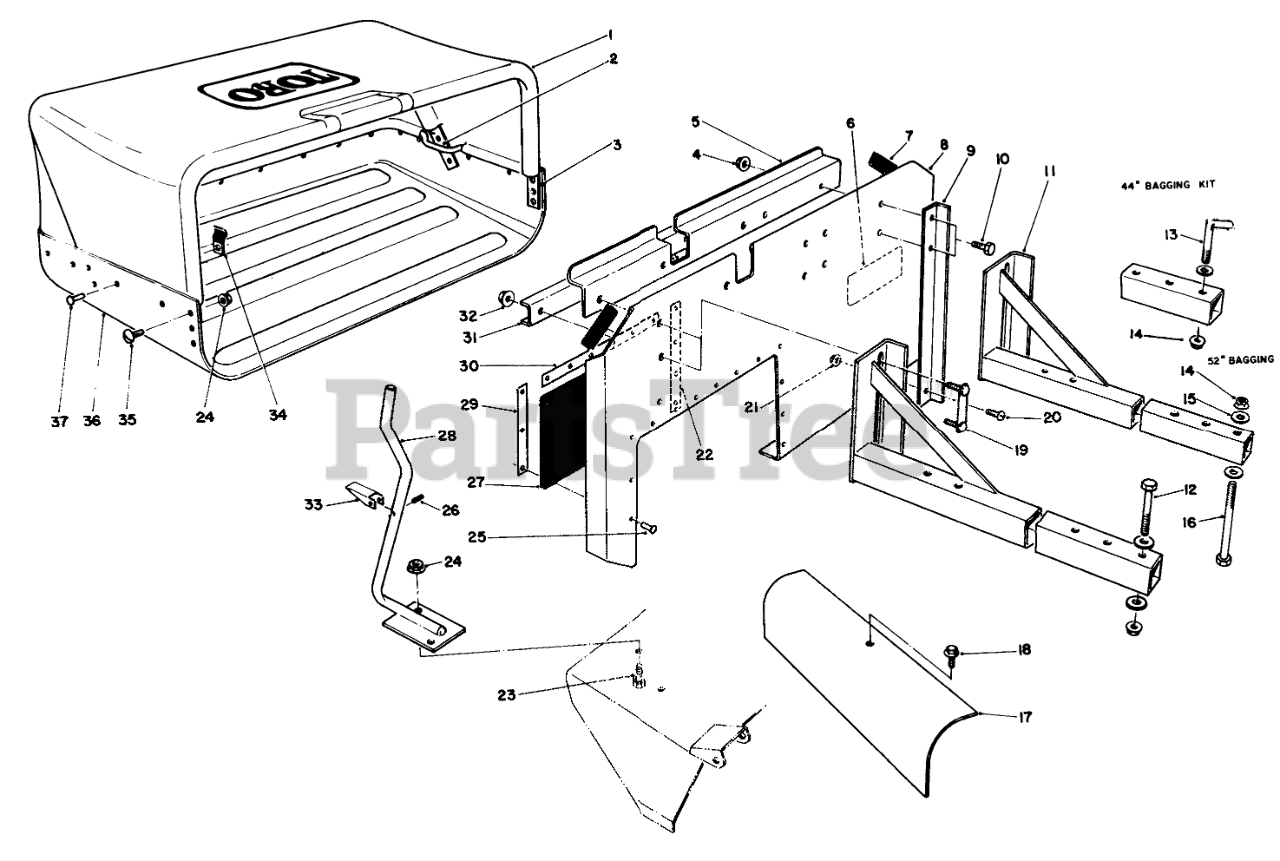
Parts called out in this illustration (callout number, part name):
1	Bag-Cloth
2	Rod-Cloth
3	Tube-Bag Support
4	NUT-HHF, WHIZ
5	Support-Bag
6	DECAL-DANGER
7	PAD-RUBBER
8	Panel-Back
9	Support-Panel
10	SCREW-HH
11	Beam-Mounting
12	SCREW-HH
13	Bolt-Special
14	NUT-LOCK, NI
15	WASHER-FLAT
16	SCREW-HH
17	Baffle-44in
18	Screw-HH
19	Retainer-Bolt
21	NUT-LOCK, HHF
22	STRIP-Seal, 10in
23	SCREW-HH
24	NUT-HF
25	RIVET-POP
26	PIN-SPRING
28	Rod-Lockup
29	STRIP
30	STRIP-SEAL, 16in
31	Support-Channel
32	NUT-LOCK, FLANGE
33	LATCH-LOCKUP
34	CLIP-HALF
35	SCREW-PPH
36	TRAY-BAG, GRASS
37	WASHER-SPRING
